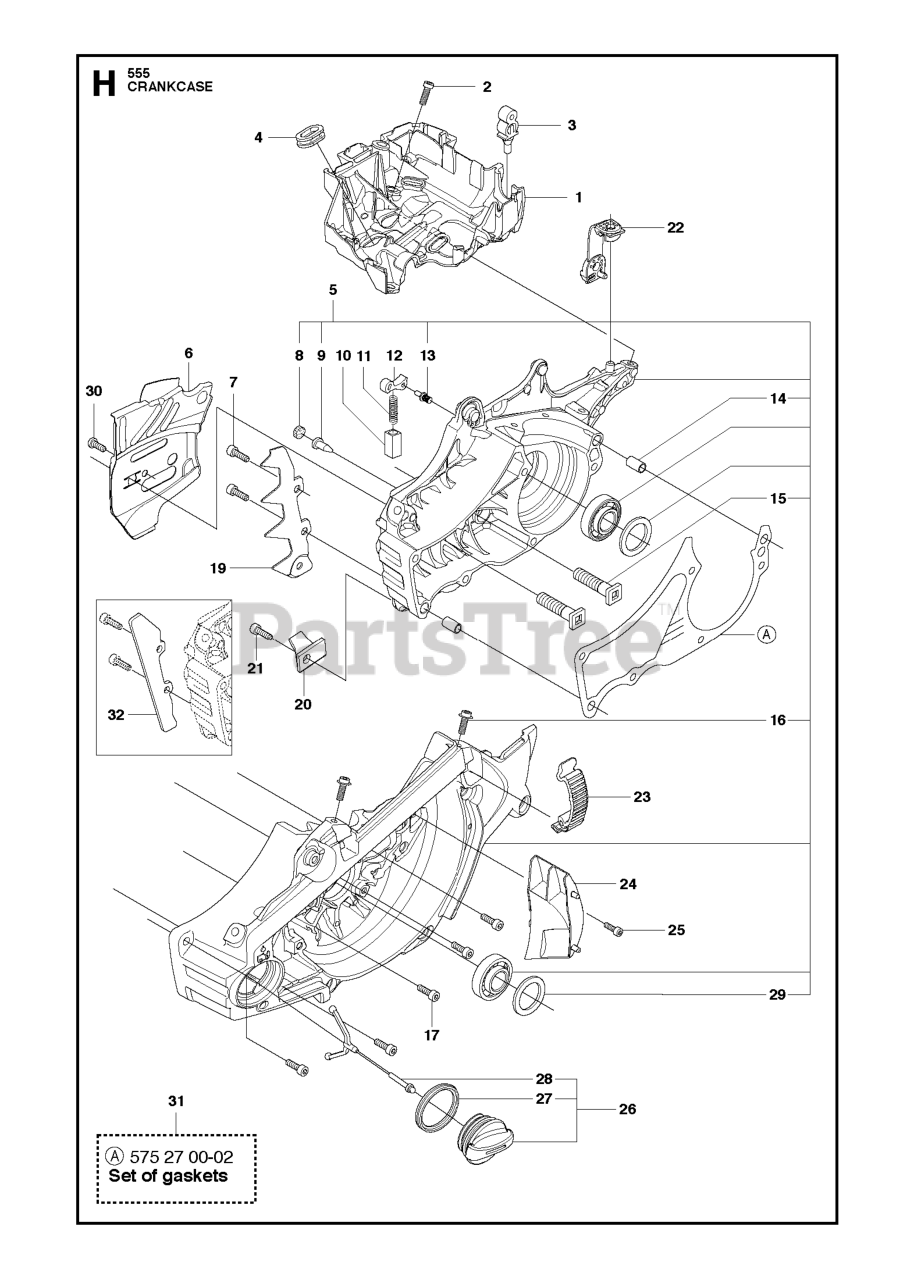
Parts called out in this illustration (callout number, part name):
1	CARBURETTOR AREA BASE
3	SUPPORT
5	RP CRANKCASE ASSY
6	CHAIN GUIDE PLATE
8	PLUG
9	VALVE-CHECK (DUCKBILL)
11	LOCK SPRING
13	PIN
14	SLEEVE
15	BAR BOLT
16	SCREW IHSCM
17	SCREW IHSCM
20	CHAIN CATCHER
22	DEFLECTION LIMITER
23	BUCKLE ORANGE
24	AIR NOZZLE
25	SCREW IHSCM
26	TANK CAP ASSY
27	SEALING
28	HOLDER
29	RADIAL SEAL
30	SCREW CITXPANT
31	GASKET KIT
32	RP ENCLOSED KIT
